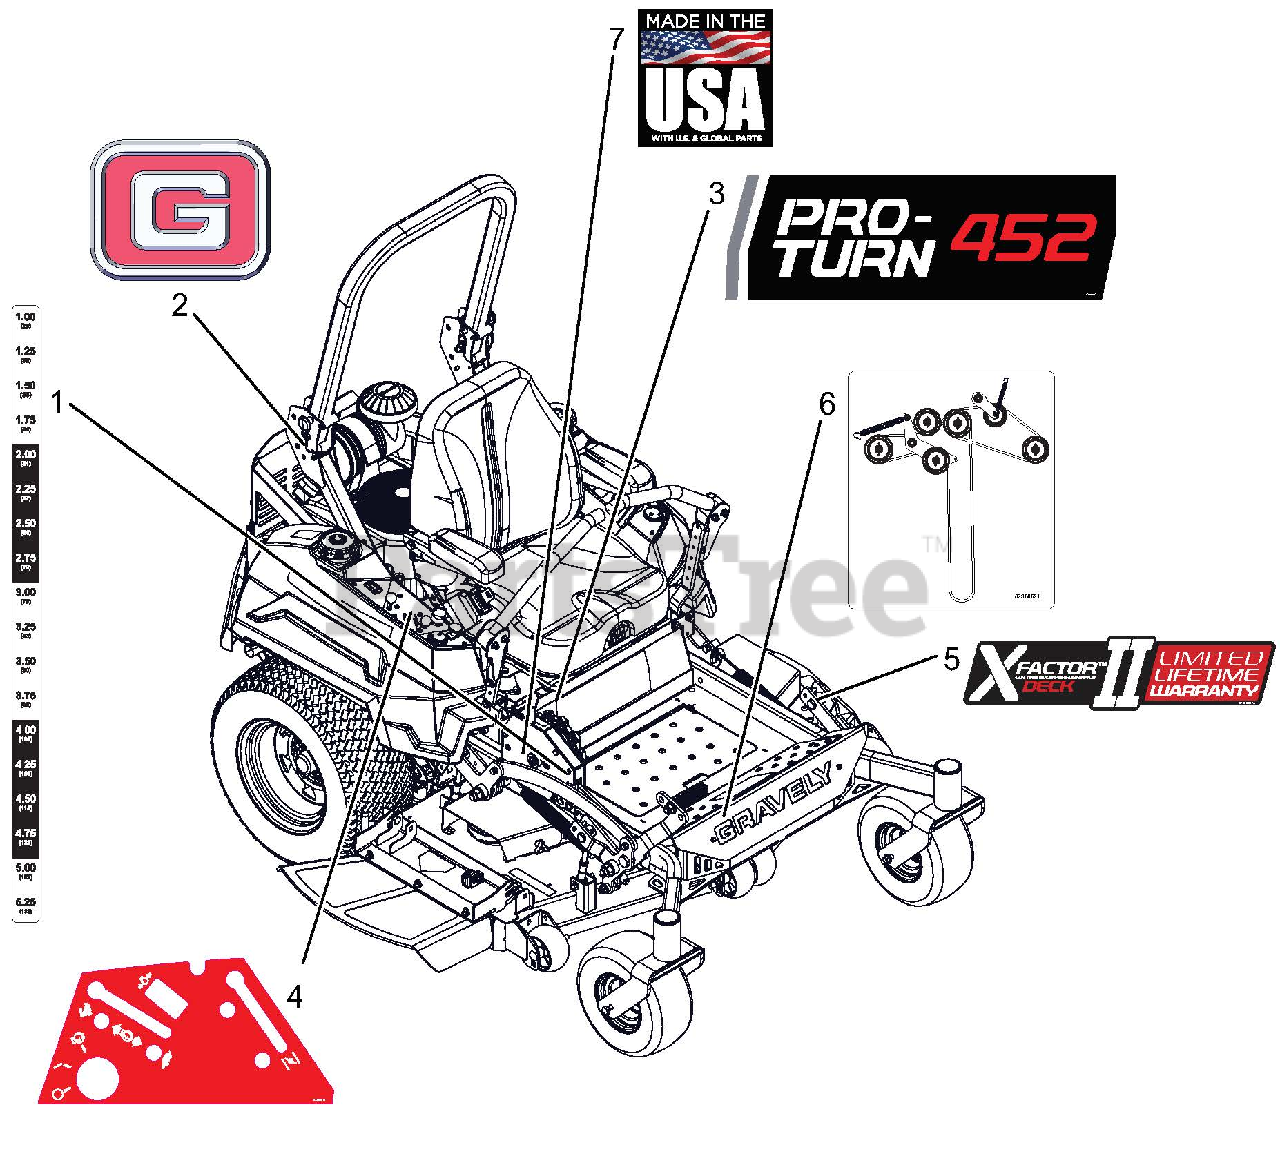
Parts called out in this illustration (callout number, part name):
1	DECAL, PT400 HEIGHT OF CUT
2	DECAL, GRAVELY BRAND
3	DECAL, PRO-TURN 452
4	DECAL, NON-EFI CONTROL PANEL
5	DECAL, X-FACTOR DECK
6	DCL,BELT ROUTE-RH V-SIDE IDLER
7	DECAL, MADE IN USA
